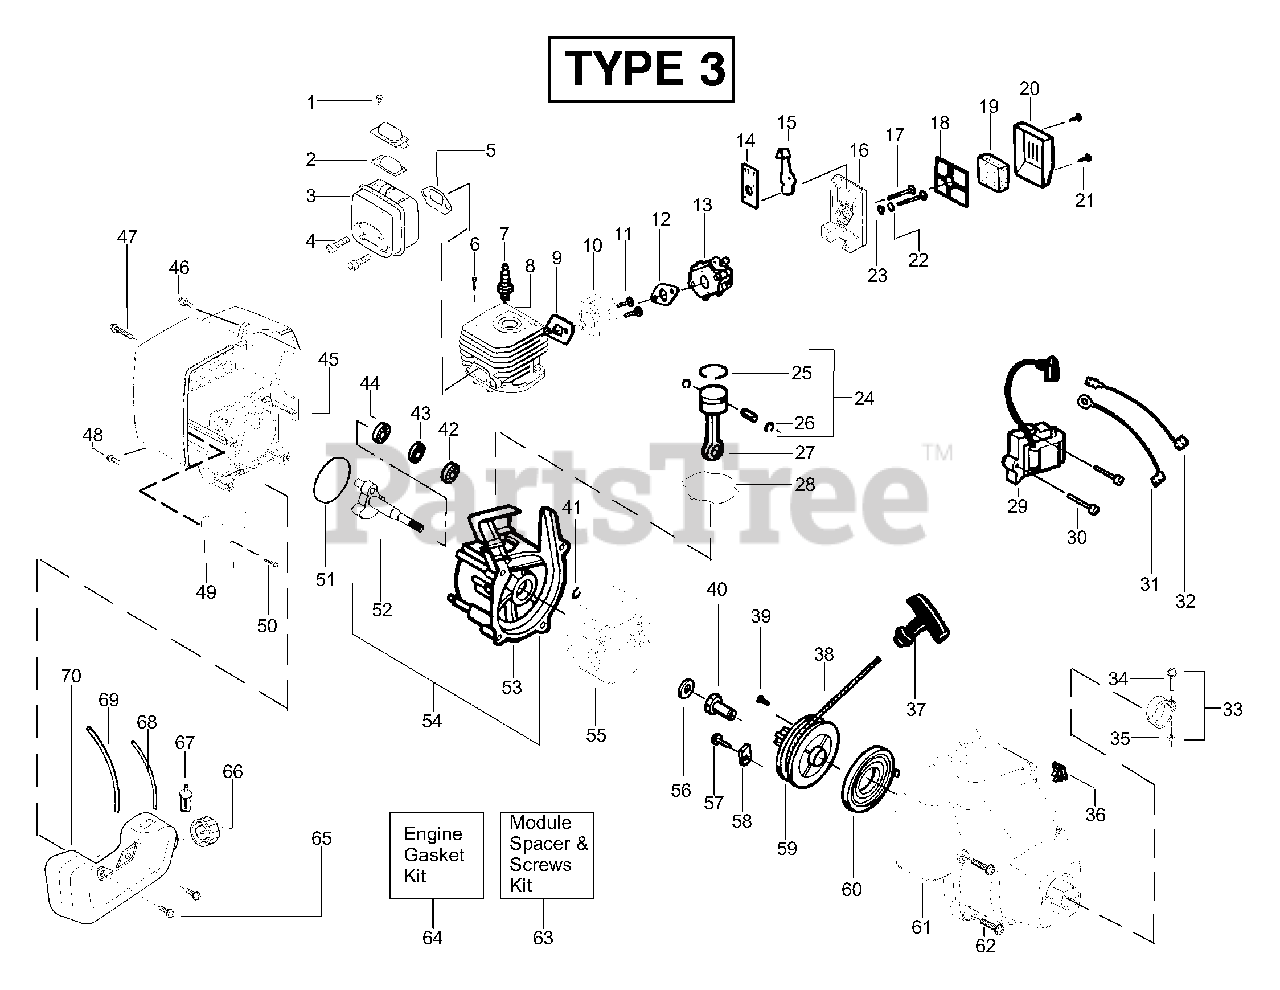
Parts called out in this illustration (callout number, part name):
1	Screw-Screen
2	Kit-Spark Arrestor
3	Kit-Muffler
4	Bolt-Muffler
5	Gasket-Muffler (kit)
6	Screw-Cylinder
7	Spark Plug (RCJ-6Y)
8	Kit - Cylinder
9	Gasket-Cyl./Carb. (kit)
10	Adapter-Carb.
12	Gasket-Carb. (kit)
13	Kit - Carburetor Ass'y (C1U-W10B)
14	Choke Plate Mounting
15	Shutter-Choke
18	Plate - Filter Support
19	Foam-Air Filter
20	Cover-Air Filter
22	Spacer-Choke
24	Kit - Piston
25	Piston Ring
26	Retainer-Piston Pin
27	Assy-Connecting Rod
28	Seal-Cylinder (kit)
29	Ignition Module
31	Assy-Ground Wire
32	Assy-Leadwire
33	Assy-Nose Cone Clamp
34	Screw-Nose Cone
35	Nut-Nose Cone
36	Kit-Switch
37	Handle-Starter
38	Kit - Rope
40	Coupling-Drive
41	Retain. Ring-C'shaft
42	Outer Bearing
43	Kit-C'case Seal
44	Inner Bearing
45	Shroud-Rear
47	Screw
49	Shield-Heat
50	Screw
51	O-Ring-C'case (kit)
52	Assy-Crankshaft
53	Assy-Crankcase
54	Assy-C'case & C'shaft
55	Assy-Flywheel
56	Washer-Flat
58	Retainer-Can
59	Kit-Starter Pulley
60	Spring-Starter
61	Assy.-Fan Hsg
62	Screw
63	Kit-Module Spacer & Screws
64	Kit-Engine Gasket
65	Retainer
66	Assy-Fuel Cap
67	Assy-Fuel Pickup
68	Kit-Fuel Line (Small)
69	Kit-Fuel Line (Large)
70	Assy-Fuel Tank
